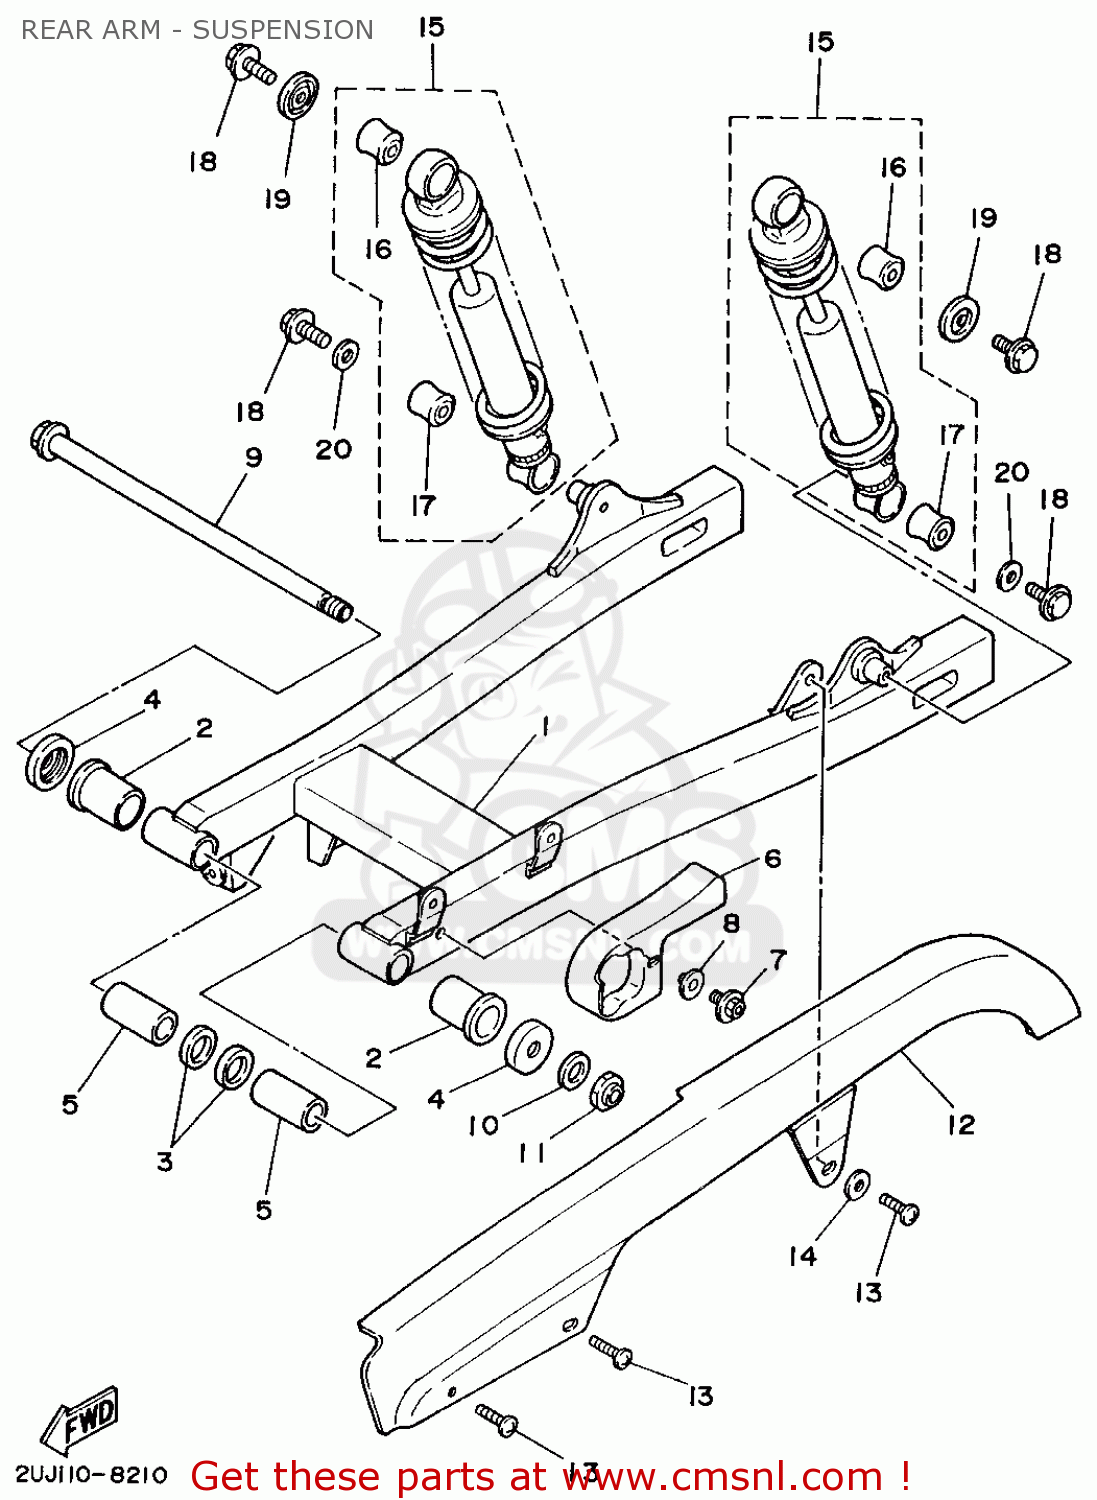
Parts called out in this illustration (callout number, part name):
1	REAR ARM COMP.
2	BUSH(3DM)
3	OIL SEAL (2J5)
4	COVER, THRUST 2
5	BUSH, SOLID (31J)
6	SEAL, GUARD
7	BOLT, WITH WASHER (10V)
8	WASHER (14U)
9	SHAFT, PIVOT
10	WASHER, PLAIN(2UJ)
11	NUT, SELF-LOCKING(2UJ)
12	CASE, CHAIN
13	SCREW, BIND(3DM)
14	WASHER, PLATE (J18)
15	SHOCK ABSORBER ASSY, REAR
16	DAMPER, SHOCK ABSORBER LOWER
17	BUSH, REAR SHOCK ABSORBER
18	BOLT, FLANGE(2UJ)
19	WASHER 1
20	WASHER, PLATE(3DM)
